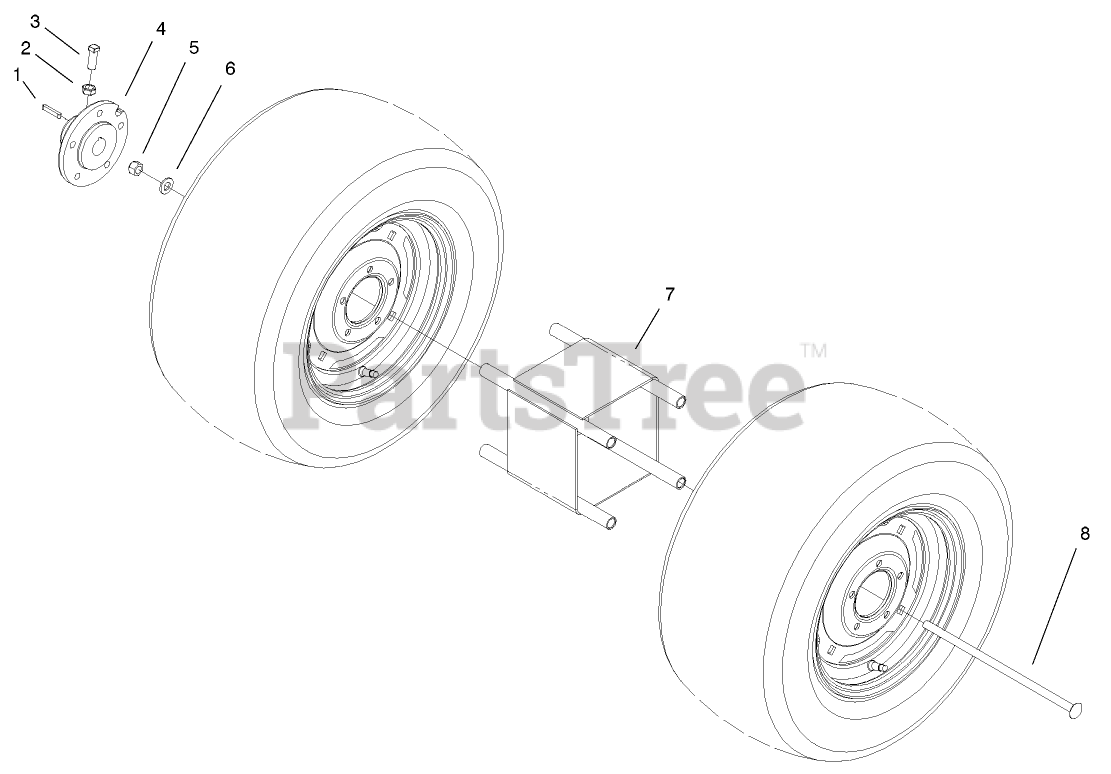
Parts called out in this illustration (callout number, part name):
2	NUT-JAM
3	SCREW-SET, SQH
4	HUB-WHEEL
5	NUT-LOCK, NI
6	WASHER-FLAT
7	ADAPTER
8	BOLT-CARRIAGE
